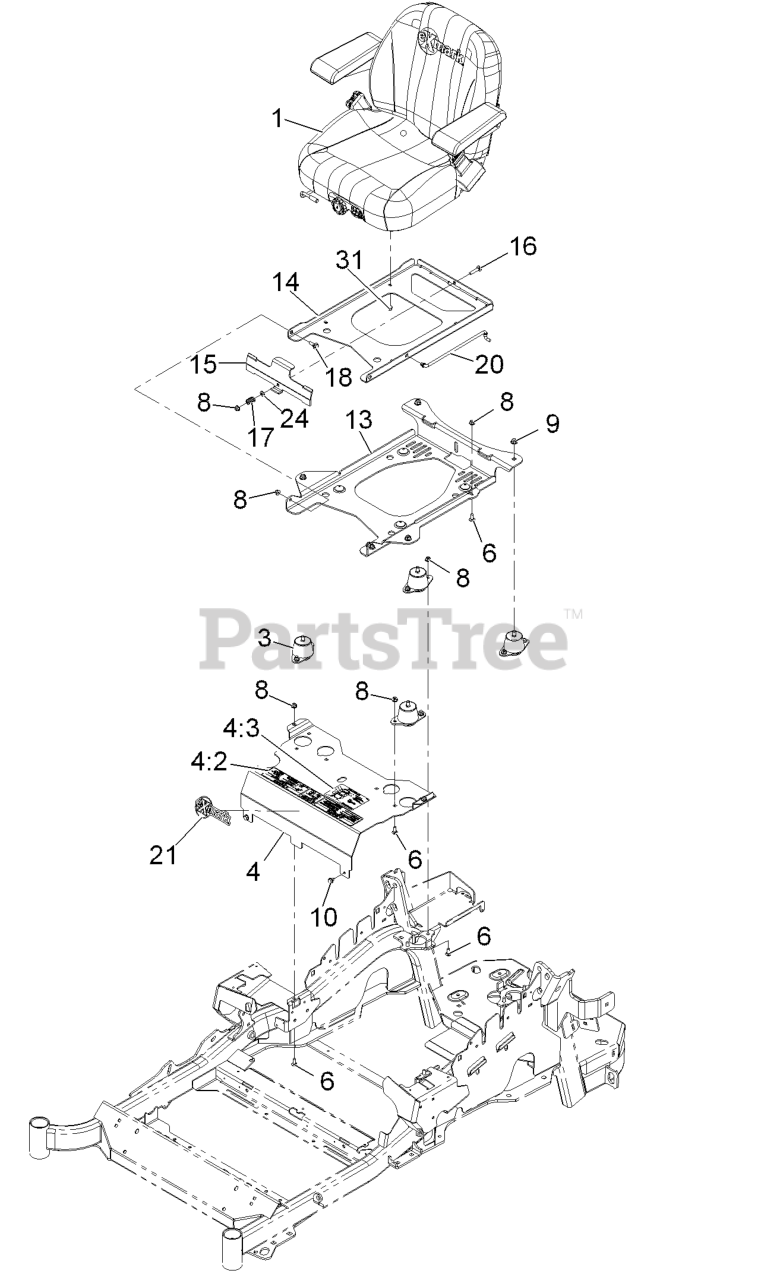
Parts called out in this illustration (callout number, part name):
3	ISOLATOR-SEAT
4	MOUNT-SEAT
4:2	DECAL-CONSOLE
4:3	DECAL-SERVICE AID
6	SCREW-CARR
8	NUT-HF, NI
9	NUT-HF, NI
13	PLATE-SUPPORT, SEAT TILT
14	PLATE-FRAME, SEAT TILT
15	PLATE-LATCH, SEAT
16	BOLT-CARR
17	SPRING-COMPRESSION
18	SCREW-SHOULDER
20	ROD-PROP
24	WASHER-PLAIN
